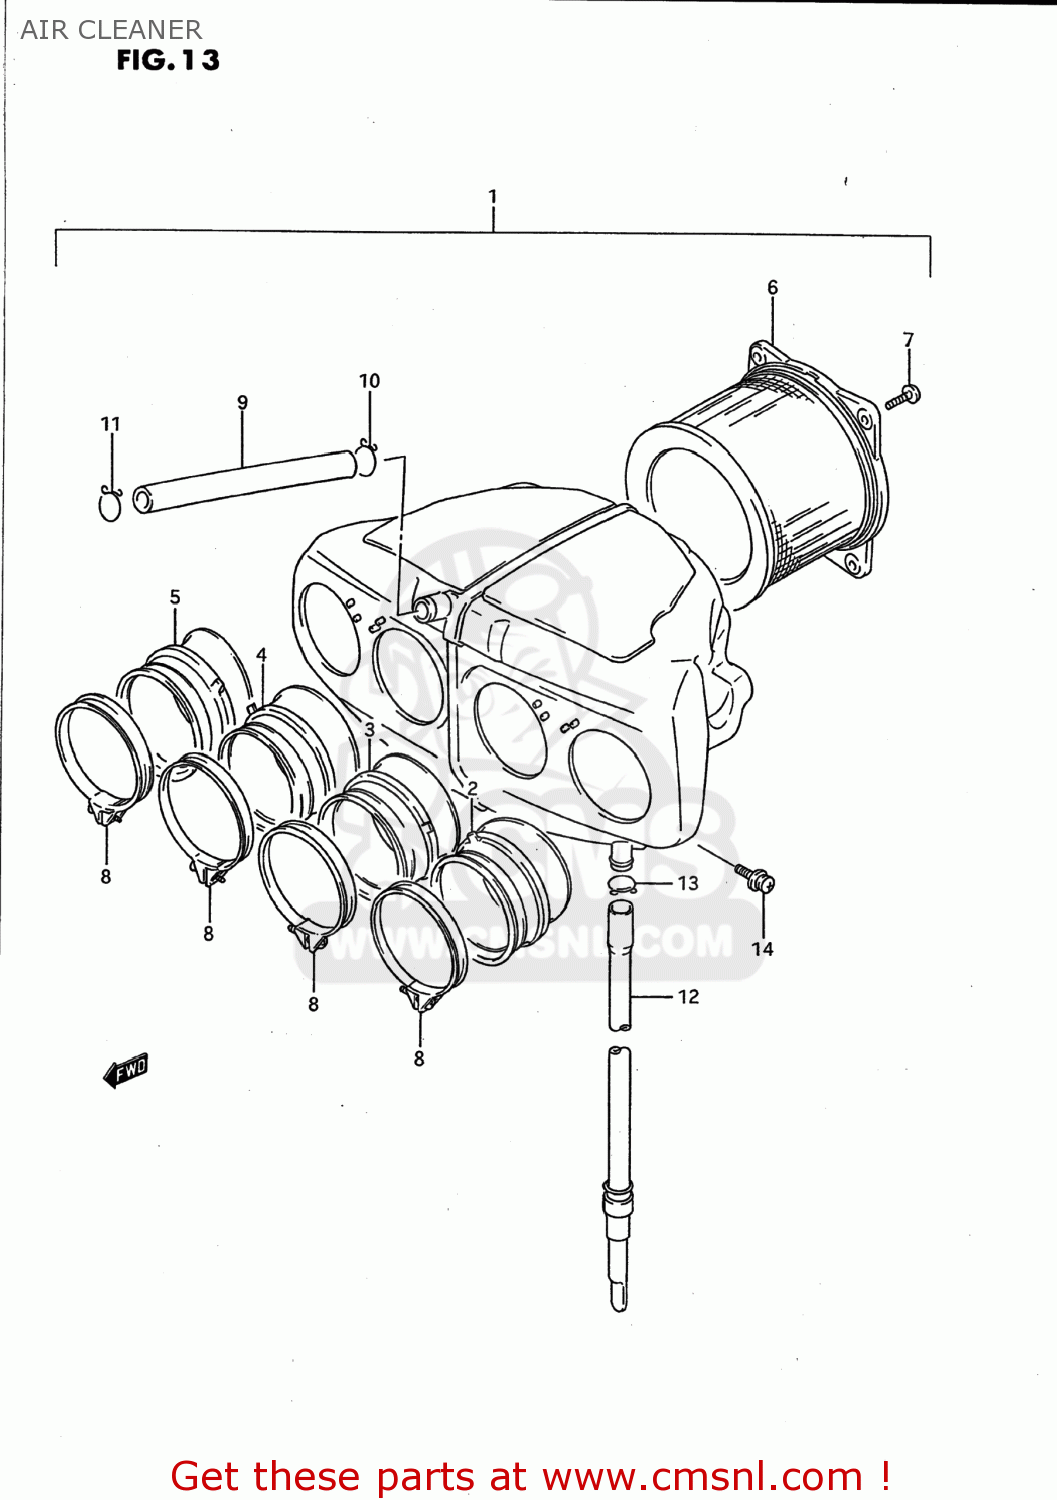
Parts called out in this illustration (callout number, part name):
1	CLEANER ASSEMBLY,AIR
2	TUBE,OUTLET,L
3	TUBE,OUTLET ML
4	TUBE,OUTLET MR
5	TUBE
6	FILTER ASSY
7	SCREW 5X12
8	CLAMP
9	TUBE,BREATHER
10	CLIP
11	CLIP
12	DRAIN TUBE
13	CLIP
14	SCREW
